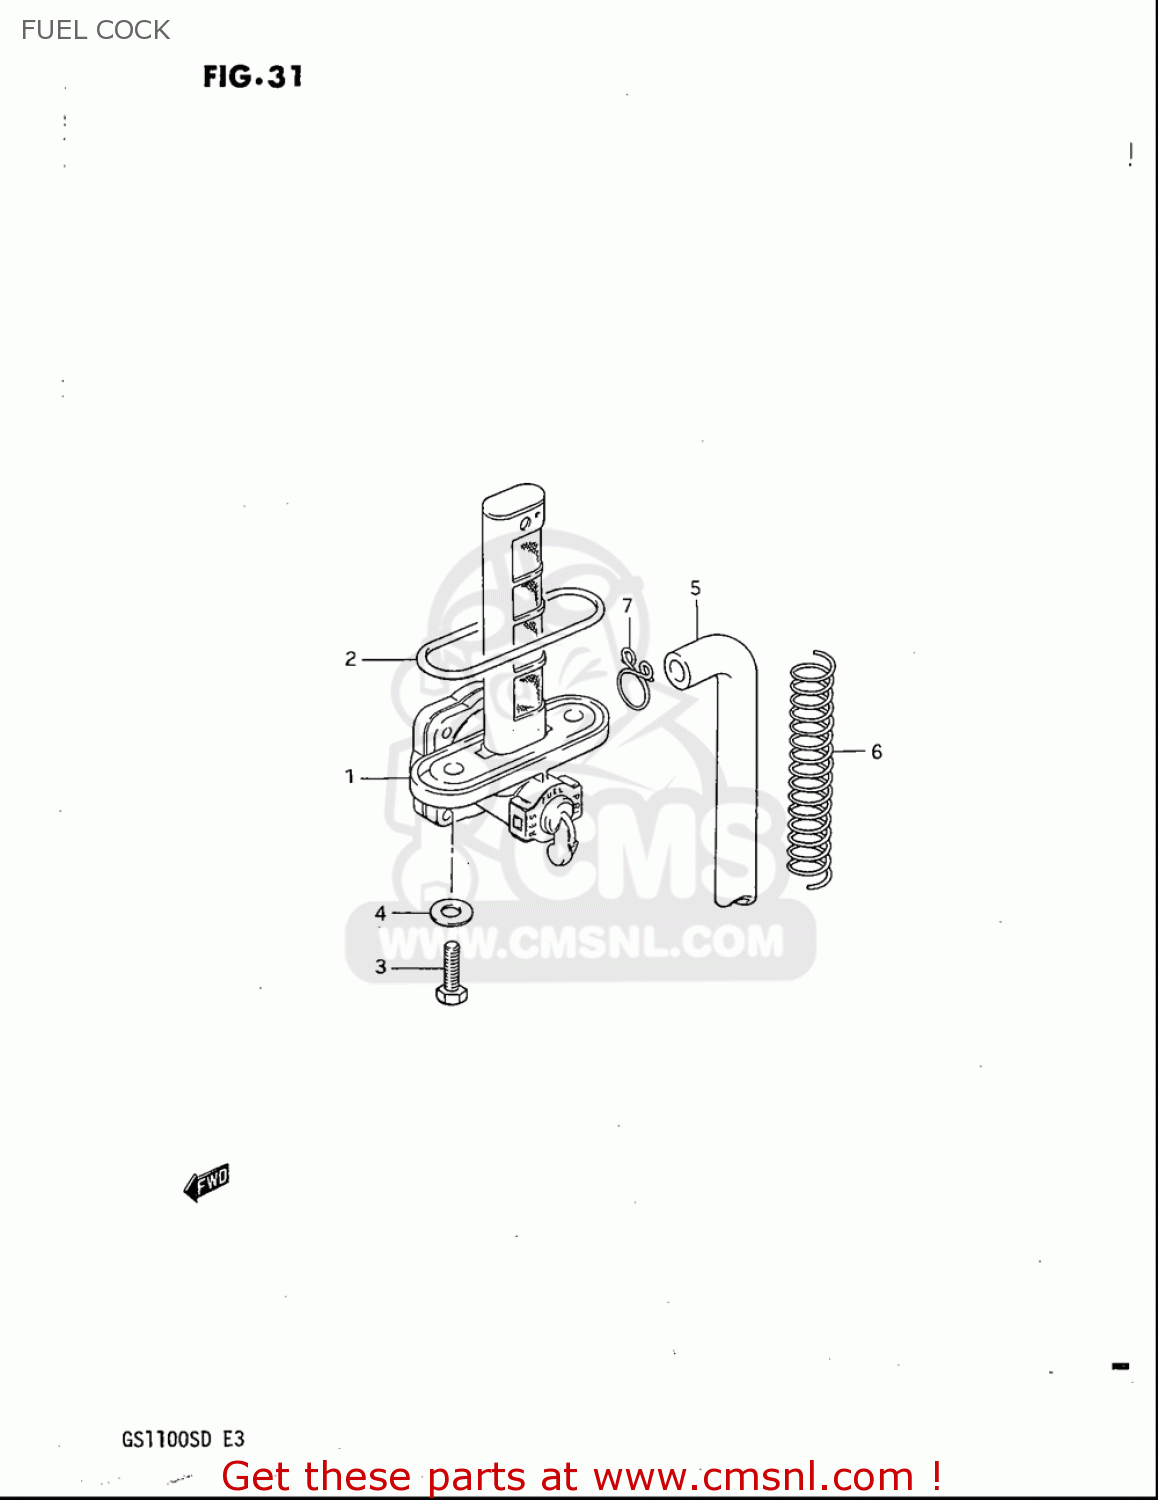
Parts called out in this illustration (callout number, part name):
1	COCK ASSY,FUEL
2	O RING
3	BOLT(6X20)
4	GASKET(5.8X13X1.2) (NAS)
5	HOSE(7X10.2X2000)
6	SPRING
7	CLIP
